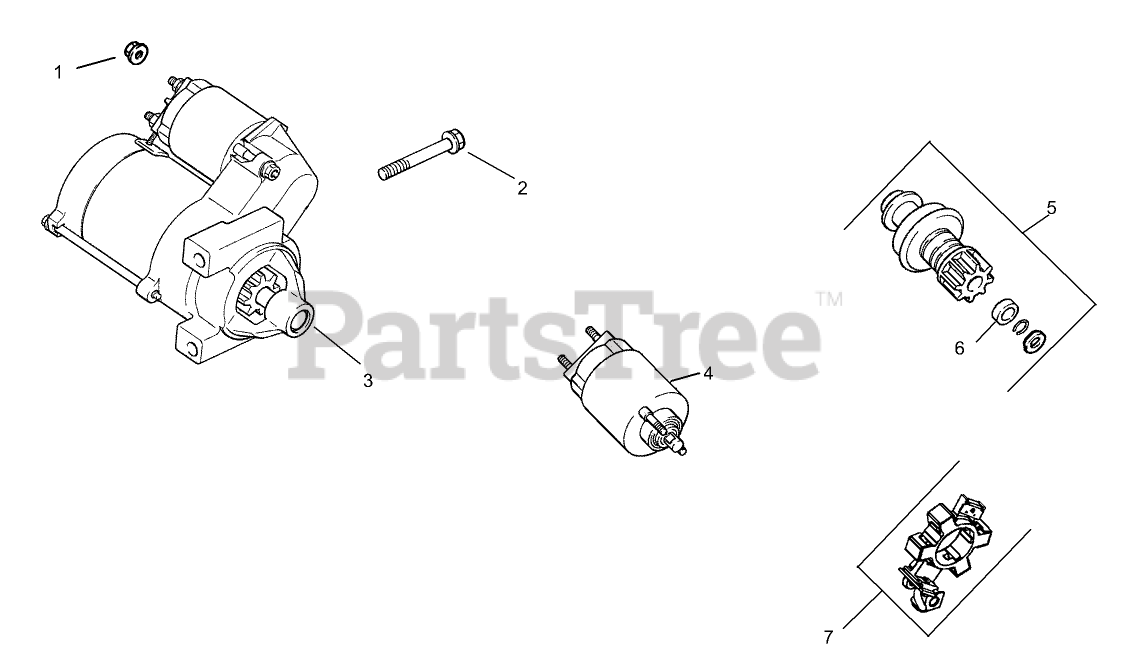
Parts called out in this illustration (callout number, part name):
1	NUT-FLANGE (M8X1.25)
2	SCREW-FLG (M8X1.25X80)
3	STARTER ASM (SOLENOID SHIFT)
4	Solenoid Kit
5	Kit-Drive, Pinion (Includes Ref # 6)
6	RING-RETAINING
7	BRUSH HOLDER KIT
